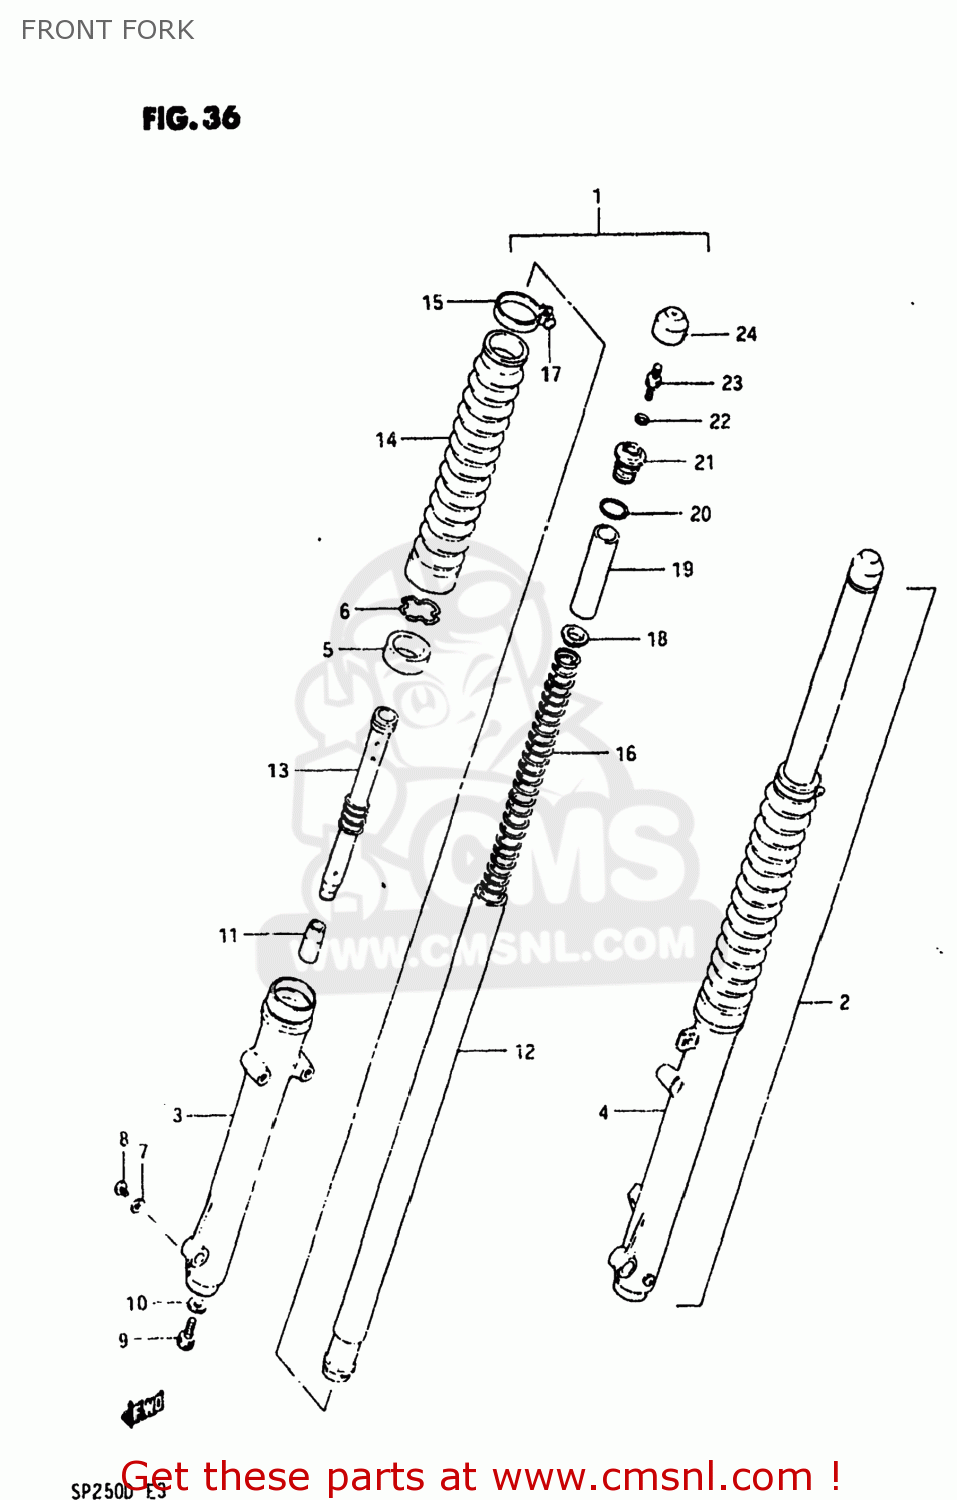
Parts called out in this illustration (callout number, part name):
1	DAMPER ASSEMBLY,RIGHT
2	DAMPER ASSEMBLY,LEFT
3	TUBE,FORK,OUTER,RIGHT
4	TUBE,FORK,LEFT,OUTER
5	SEAL,OIL
6	7
7	GASKET,DRAIN,PLUG (NAS)
8	SCREW
9	BOLT,FORK CYLINDER(10X25)
10	GASKET (NAS)
11	PIECE,OIL LOCK
12	TUBE,INNER
13	CYLINDER,FRONT FORK
14	BOOT
15	BAND,BOOT
16	SPRING
17	SCREW
18	GUIDE,FRONT FORK SPRING C
19	COLLAR,SPRING
20	O RING
21	CAP,FORK INNER TUBE
22	O-RING
23	VALVE,FRONT FORK AIR
24	CAP
